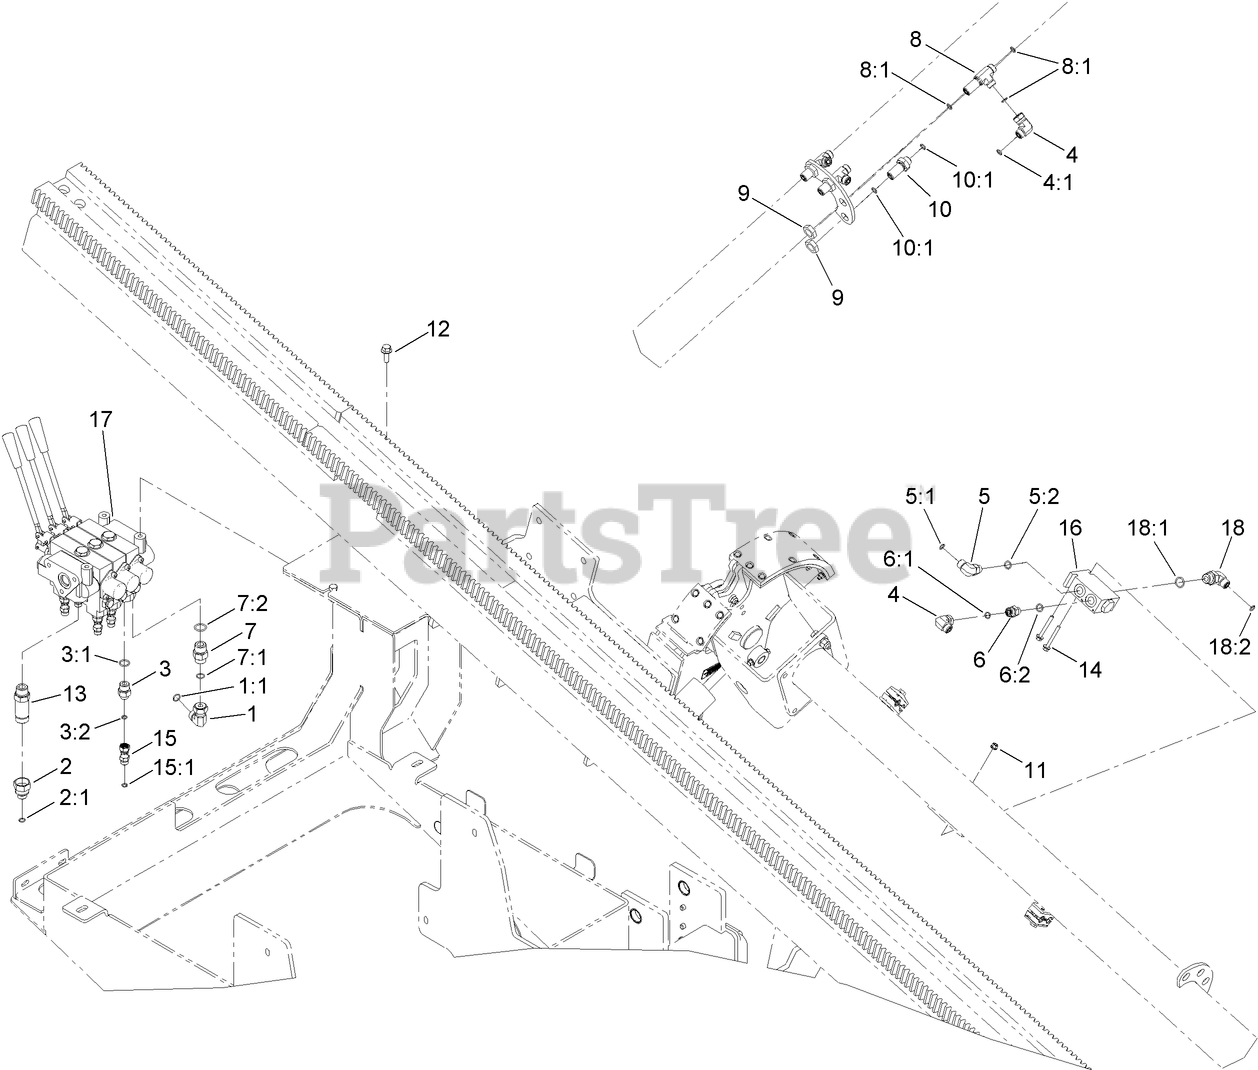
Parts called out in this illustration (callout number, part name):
1	FITTING-HYD
1:1	O-RING
2	FITTING-HYD
2:1	O-RING
3	FITTING-STR
3:1	O-RING
3:2	O-RING
4	FITTING-HYD, 90 DEG
4:1	O-RING
5	FITTING-ELBOW, 90 DEG
5:1	O-RING
5:2	O-RING
6	FITTING-STRAIGHT
6:1	O-RING
6:2	O-RING
7	FITTING-STRAIGHT
7:1	O-RING
7:2	O-RING
8	FITTING-TEE, BULKHEAD
8:1	O-RING
9	NUT-LOCK
10	FITTING-STRAIGHT, BULKHEAD
10:1	O-RING
11	NUT-FLANGE, NI
12	SCREW-HHF
13	CONNECTOR
14	SCREW-HHF
15	FITTING-STRAIGHT
15:1	O-RING
16	HYD FLOW DIVIDER VALVE ASM
17	3 SPOOL HYD VALVE ASM
18	FITTING-HYD, 90 DEG
18:1	O-RING
18:2	O-RING
